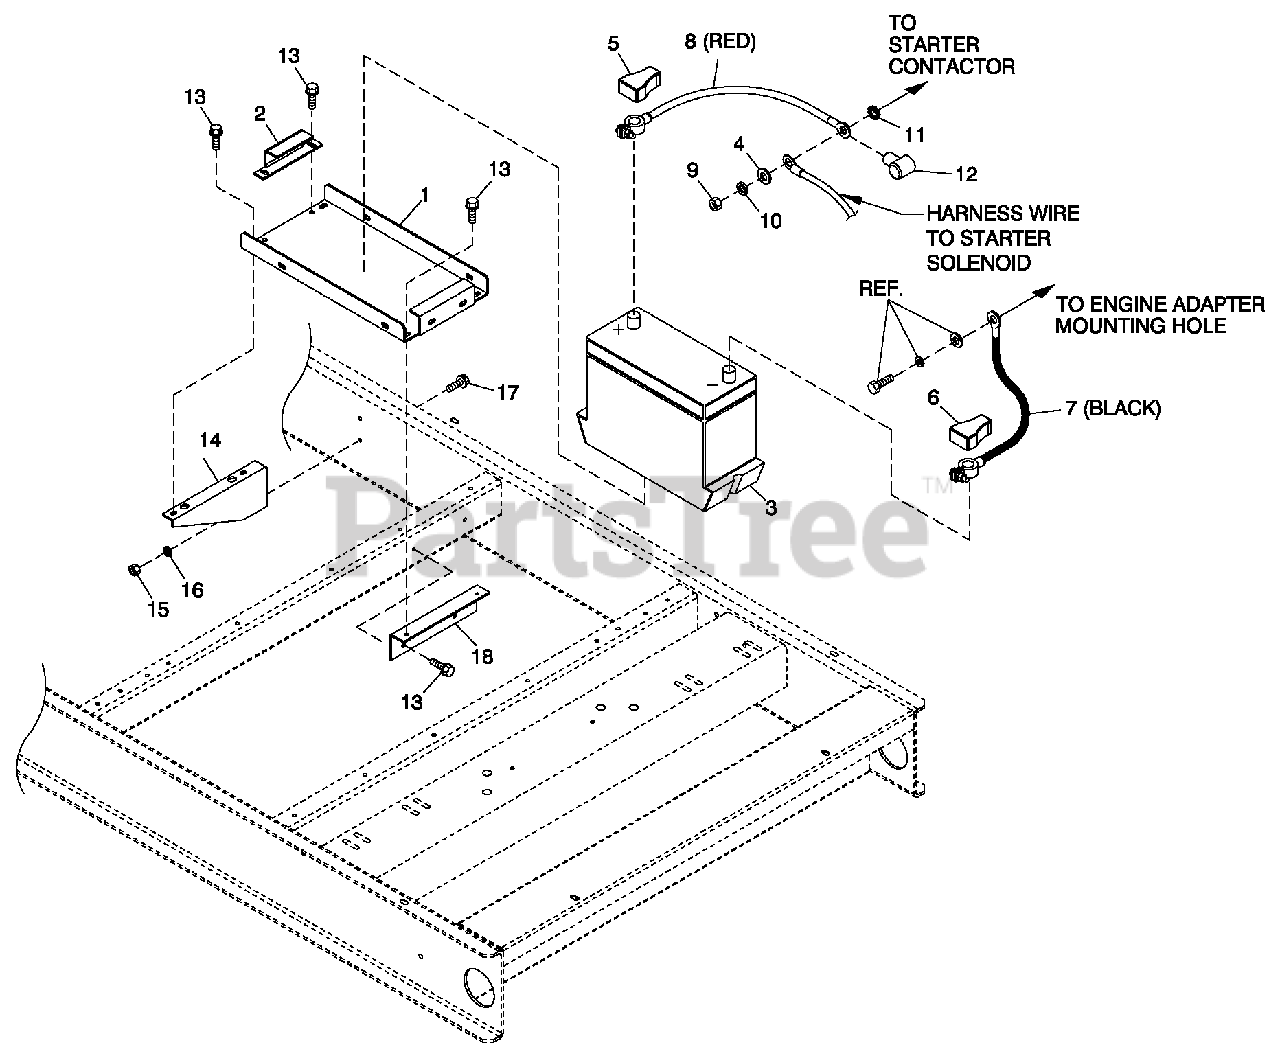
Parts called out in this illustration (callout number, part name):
1	TRAY BATTERY 27F
2	STRAP BATTERY RETAINMENT 27F
3	BATTERY 12VDC 90-AH 27F
4	WASHER FLAT 3/8-M10 ZINC
5	BATTERY POST COVER RED +
6	BATTERY POST COVER BLK -
7	CABLE BATTERY BACLK #1 X 26.00
8	CABLE BATTERY RED #1 X 28.00
9	NUTHEXM8-1.25 G8YEL CHR
10	WASHER LOCK M8-5/16
11	WASHER SHAKEPROOF EXT 5/16 STL
12	BOOT BATTERY CABLE
13	SCREW THF M6-1 X 16 N WA Z/JS
14	SUPPORT BATTERY TRAY
15	WASHER LOCK M6-1/4
16	NUT HEX M6X 1.0 G8YEL CHR
17	SCREW HHC M6-1.0X 20 G8.8
18	SUPPORT 27F BATTERY
